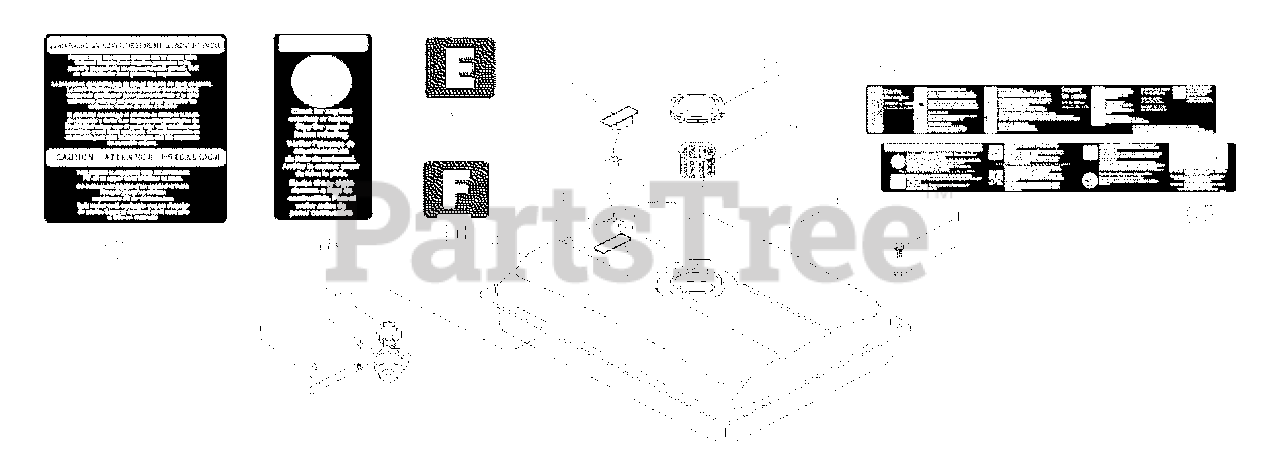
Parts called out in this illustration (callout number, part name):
37	fuel laek label
38	far from fire label
39	Fuel tank empty
40	Fuel tank Full
41	Quick start label
105	Warning label
131	Fuel hose
132	Fuel hose clip
133	Fuel valve
134	Fuel meter
135	Fuel cap
136	Fuel filter
137	Fuel tank
138	M6 x 12 bolt
